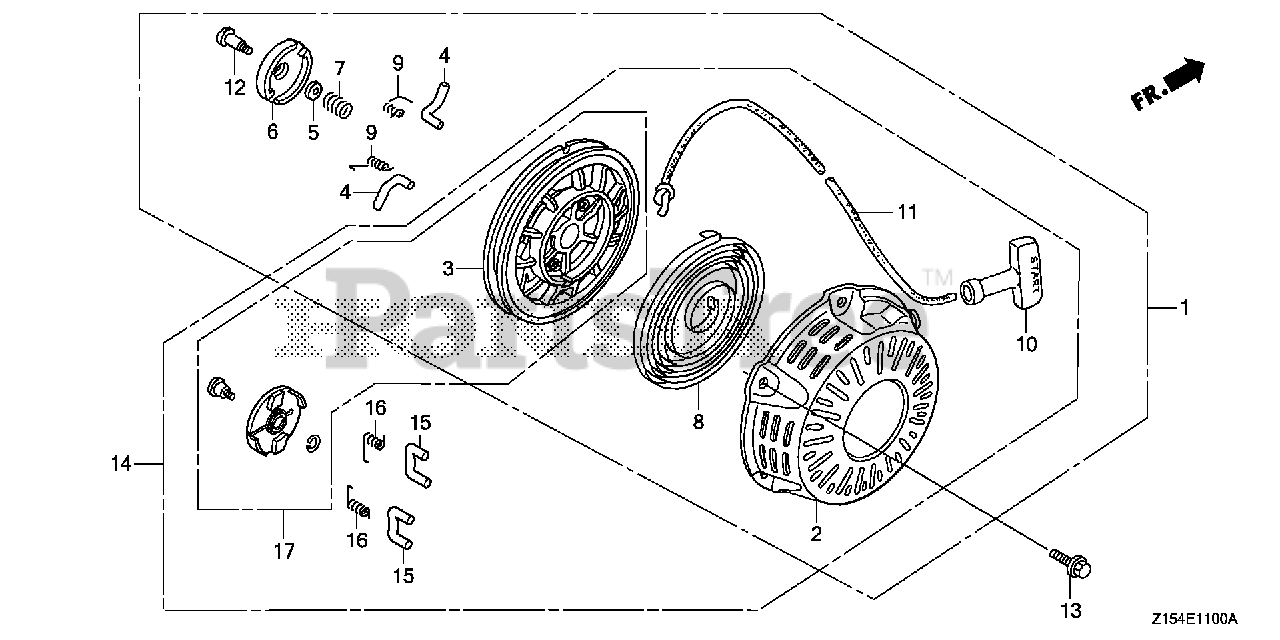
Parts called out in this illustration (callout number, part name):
1	STARTER ASSY., RECOIL *NH1* (BLACK)
2	CASE, RECOIL STARTER *NH1* (BLACK)
3	REEL, RECOIL STARTER (BLACK)
3	REEL, RECOIL STARTER
4	RATCHET, STARTER
5	PLATE, FRICTION
6	GUIDE, RATCHET
7	SPRING, FRICTION
8	SPRING, RECOIL STARTER
9	SPRING, RETURN
10	GRIP, STARTER
10	KNOB, RECOIL SRARTER
11	ROPE, RECOIL STARTER
12	SCREW, SETTING
13	BOLT, FLANGE (6X10)
14	STARTER ASSY., RECOIL *NH1* (BLACK)
15	RATCHET, STARTER
16	SPRING, RETURN
17	STARTER SET, RECOIL
